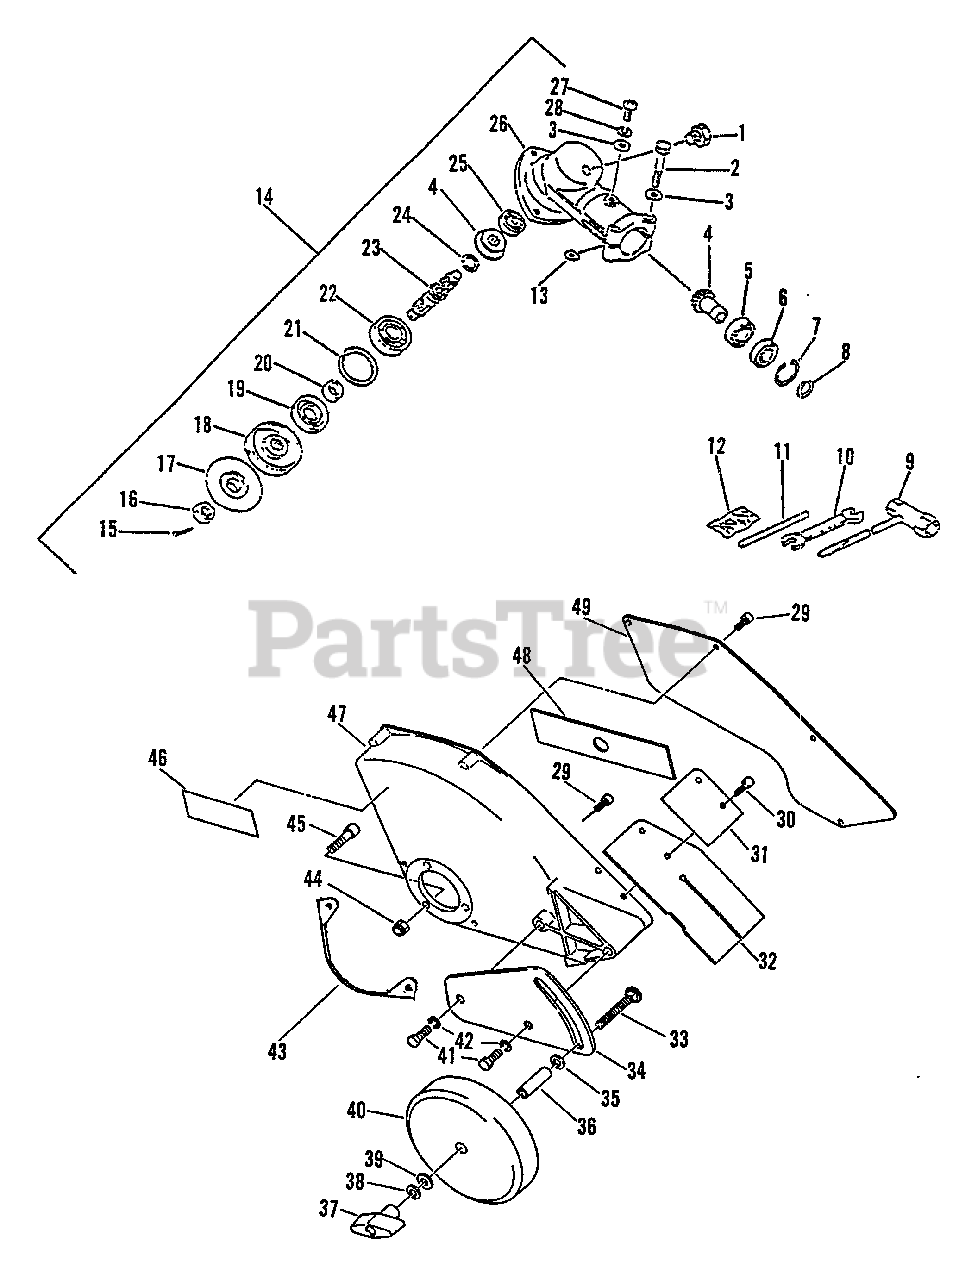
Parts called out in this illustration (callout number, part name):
1	BOLT 8×8 SP
2	BOLT 5×35 SP
3	WASHER, FLAT 5.5×10×0.8
4	GEAR SET
5	BEARING, BALL 6900
6	BEARING, BALL 6900Z
7	RING, SNAP Ø22
8	RING, SNAP Ø12
9	T-WRENCH 17x-19 L200
10	SPANNER 8×10
11	TOOL, LOCKING 5×120 MM
12	PIN, COTTER 2×22 (PKG. OF 10)
14	GEAR CASE ASSY
15	PIN, COTTER 2×22
17	PLATE, ADAPTOR - LOWER
18	PLATE, ADAPTER - UPPER
19	SEAL, OIL 22
20	SPACER 11.8×15×9
21	RING, RETAINING - 32
22	BEARING, BALL - 6201 C3
23	SHAFT, GEAR
24	RING, RETAINING - 10
25	BEARING, BALL 609
26	HOUSING, GEAR CASE
27	SCREW 5×10
28	WASHER, SPRING 5
29	BOLT 4×10
30	BOLT 4×14
31	PLATE, FLAP
32	FLAP, DEBRIS
33	BOLT 5/16"-18×2-1/2"
34	BRACKET, WHEEL
35	WASHER, SPRING 10
36	COLLAR 12
37	KNOB, FASTENER
38	WASHER, SPRING 8
40	WHEEL
41	BOLT 8×14
42	WASHER, SPRING 8
43	WEAR PLATE
44	NUT, LOCK M5
45	BOLT 5×22
46	LABEL, CAUTION
47	NEW BLADE SHIELD
48	BLADE, EDGER
49	SHIELD, DEBRIS
